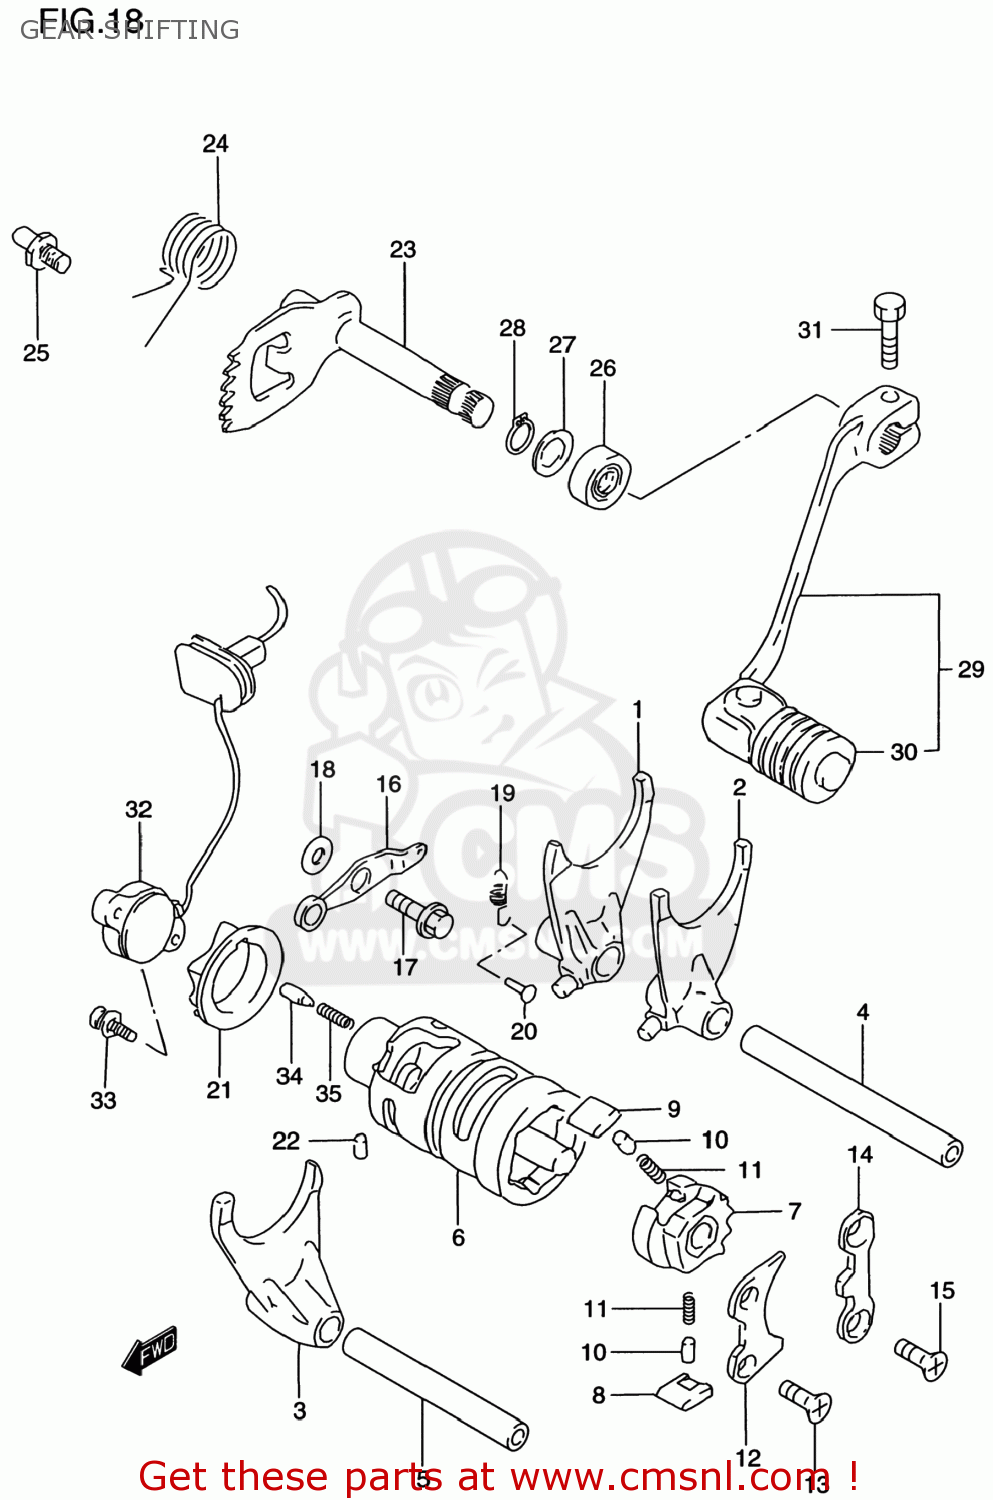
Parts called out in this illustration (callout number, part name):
1	FORK,GEAR SHIFT NO.1
2	FORK,GEAR SHIFT NO.2
3	FORK,GEAR SHIFT NO.3
4	SHAFT,GEAR SHIFT FORK
5	SHAFT,GEAR SHIFT FORK
6	CAM,GEAR SHIFT
7	GEAR,GEARSHIFT CAM DRIVE
8	PAWL,GEAR SHIFT NO.1
9	PAWL,GEAR SHIFT NO.2
10	PIN(5X8)
11	SPRING
12	LIFTER,GEAR SHAFT PAWL
13	SCREW
14	STOPPER,GEAR SHIFT POLE
15	SCREW
16	STOPPER,GEAR SHIFT CAM
17	BOLT(6X14.6)
18	WASHER
19	SPRING
20	RIVET
21	PLATE,GEAR SHIFT CAM STOPPER
22	PIN
23	SHAFT,GEAR SHIFT
24	SPRING
25	STOPPER,GEAR SHIFT CAM
26	OIL SEAL
27	WASHER
28	CIRCLIP,12 MM
29	LEVER ASSY,GEAR SHIFT
30	RUBBER,GEAR SHIFT PEDAL
31	BOLT
32	BASE ASSY,NEUTRAL SW TERMINAL
33	SCREW
34	PIN(5X15.5)
35	SPRING
